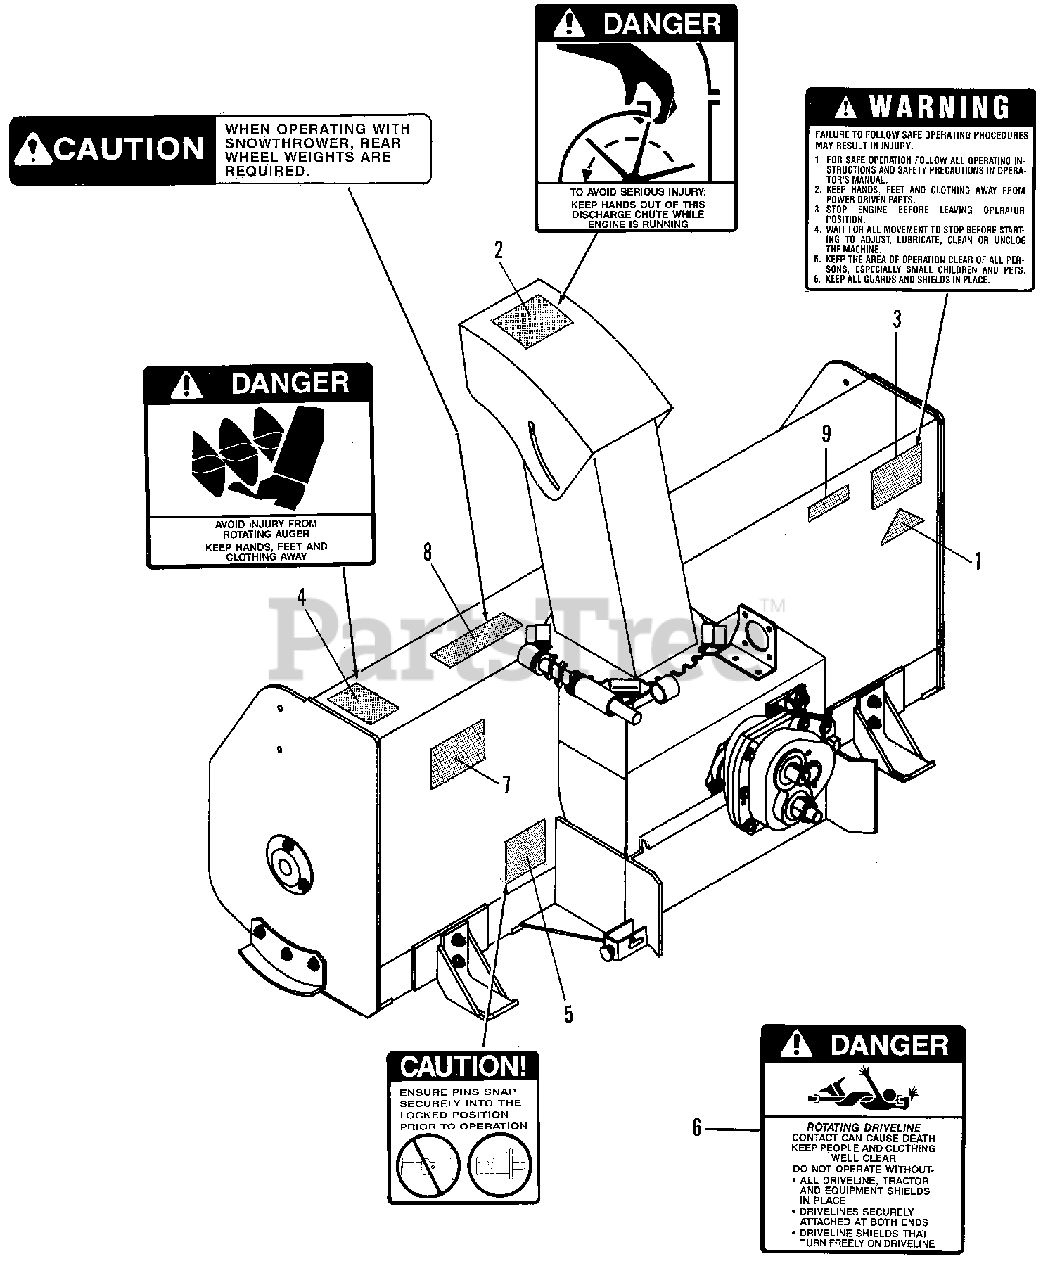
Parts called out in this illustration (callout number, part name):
1	DECAL, OPEI
2	DECAL, Danger, Blower
3	DECAL, Caution
4	DECAL, Danger, Auger
5	DECAL, Danger, Shot-Pins
6	DECAL, Danger, Rotating Driveline
7	DECAL, Important, Shear Bolt
8	DECAL, Caution, Rear Wheel Weights
9	DECAL, I.D. Plate
